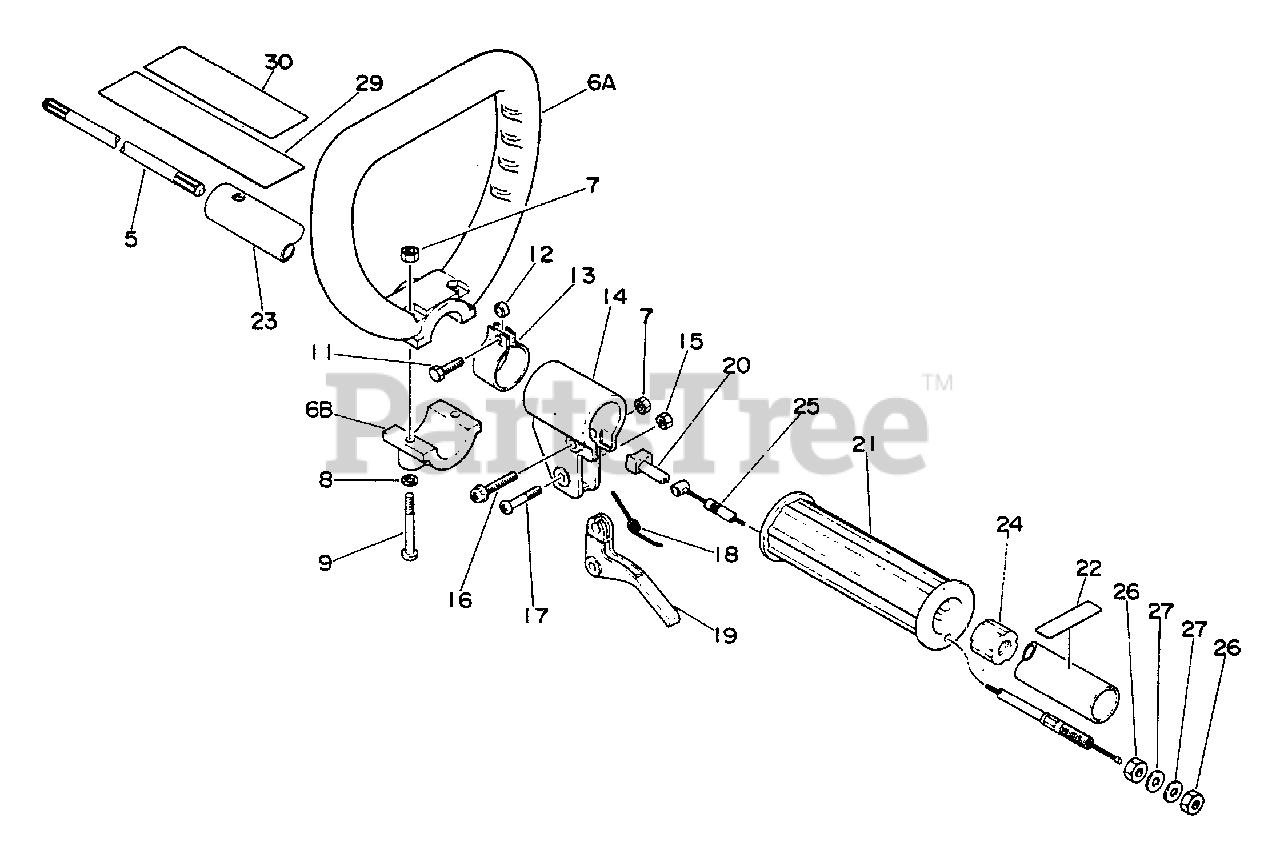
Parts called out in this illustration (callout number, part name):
5	DRIVESHAFT
6	LOOP HANDLE ASSY
6A	LOOP HANDLE ASSY
6B	LOOP HANDLE ASSY
8	WASHER - 5
9	SCREW - 5X40
11	BOLT - 5X18
14	BRACKET, TRIGGER
15	LOCKNUT - 5
16	SCREW - 5X30
17	SCREW - 5X30
18	SPRING, TRIGGER
19	TRIGGER, THROTTLE
20	GUIDE, CABLE
21	GRIP
22	LABEL - ALIGNMENT
23	MAIN PIPE ASSY
24	STOPPER
25	CABLE, THROTTLE
27	WASHER - 6
29	LABEL - CAUTION
30	LABEL - CAUTION
